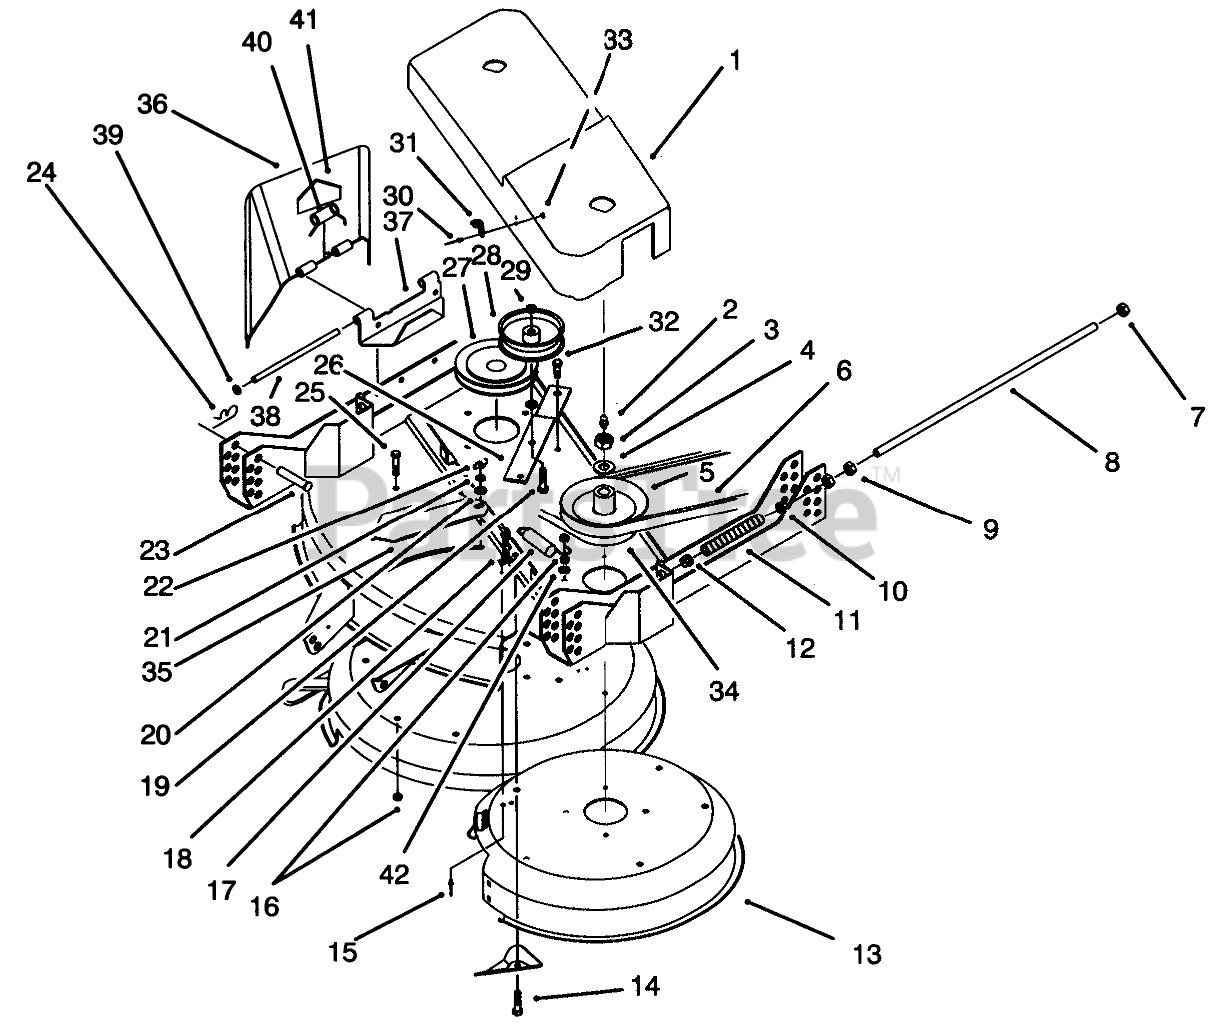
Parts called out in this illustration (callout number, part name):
1	COVER-PULLEY
2	FITTING-GREASE
3	NUT-HEX
4	WASHER
5	PULLEY-CENTER
6	V-BELT, DECK DRIVE
7	NUT-LOCK, NI
8	SHAFT-ADJUSTING
9	NUT-JAM
10	WASHER
11	SPRING
12	BUSHING-FLANGE
13	Deck (Incl. Ref. #1 & 10 on pg.1)
14	SCREW-HH
15	NUT-LOCK, NI
16	NUT-LOCK, NI
17	SPRING-EXTENSION, DECK
18	Latch Assembly (Incl. Ref. #31)
19	SCREW-HH
20	WASHER-FLAT
21	WASHER-LOCK
22	NUT-WING
23	PIN-CLEVIS
24	PIN-HAIR
25	SCREW-HH
26	Lever-Idler
27	PULLEY-OUTSIDE
28	PULLEY-IDLER
29	NUT-LOCK, NI
31	KEEPER-LATCH
32	SCREW-SHOULDER
33	WASHER-BACK
34	V-BELT, DECK
35	Cover-Slot
36	Deflector-Discharge
37	Hinge-Deflector
38	PIN-HINGE
39	RING-RETAINING, EXTERNAL
40	SPRING
41	DECAL-DANGER
42	WASHER-PLAIN
